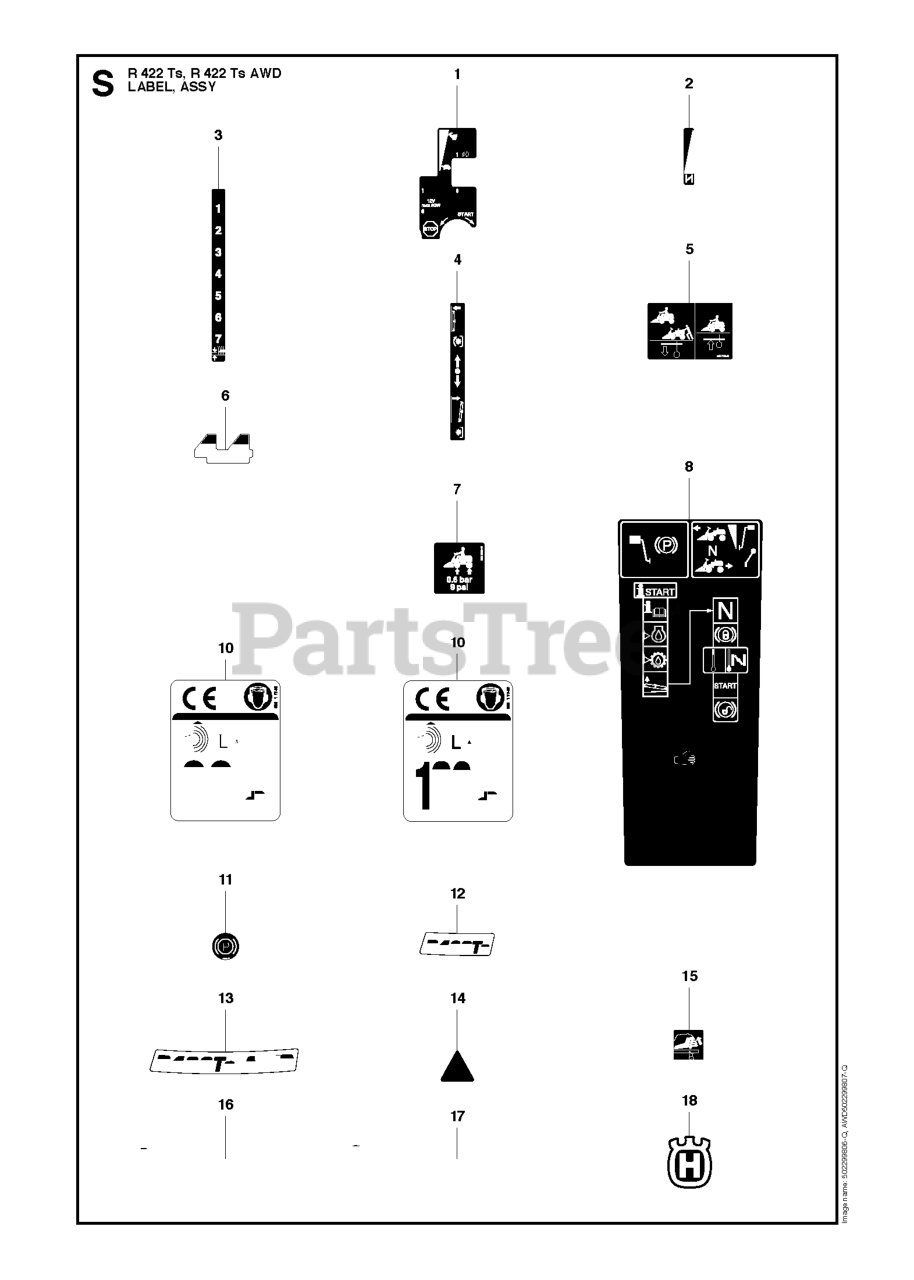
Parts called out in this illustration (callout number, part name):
5	DECAL
6	LABEL
8	Decal - Warning
11	Decal
